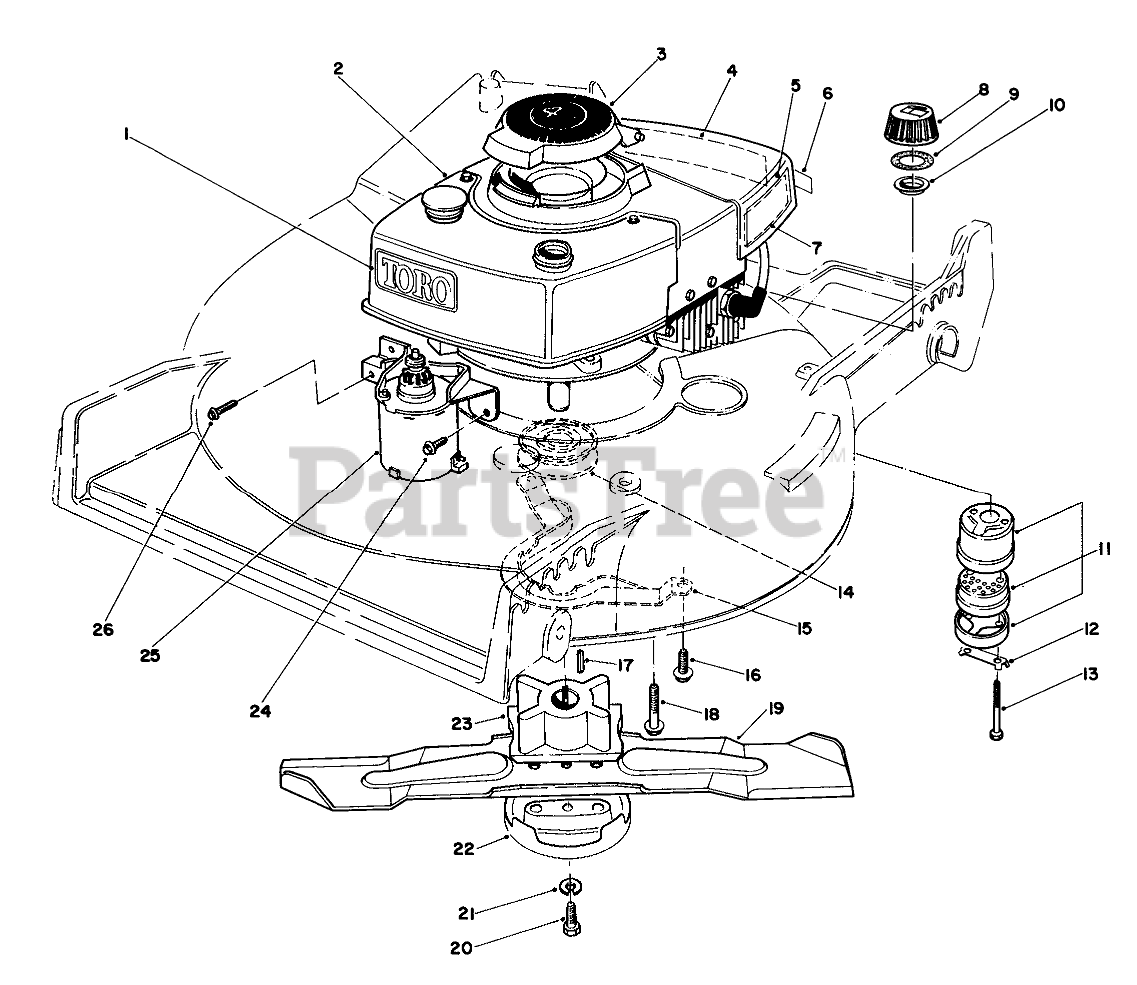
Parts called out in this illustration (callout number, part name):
1	Decal Tow
2	Engine
3	COVER ASM
4	Decal Maintenance
5	Decal-Maintenance
6	Decal-Primer Bulb
7	Decal-Maintenance
8	Gas Cap (Incl. Ref. #9 & 10)
9	GASKET
10	GAS CAP BAFFLE
11	Muffler Assembly (Incl. Ref. #12 & 13)
12	CLIP - LOCKING
13	SCREW-HH
14	Pulley
15	BELT GUIDE
16	Screw
17	KEY-SQUARE
18	3/8-16 X 2 CAPSCREW
19	BLADE-21in
20	SCREW-BLADE
21	WASHER-LOCK
22	Anti Scalp Cup
23	BLADE RETAINER(DEEP)
24	SCREW
25	Starter Motor
26	Screw
